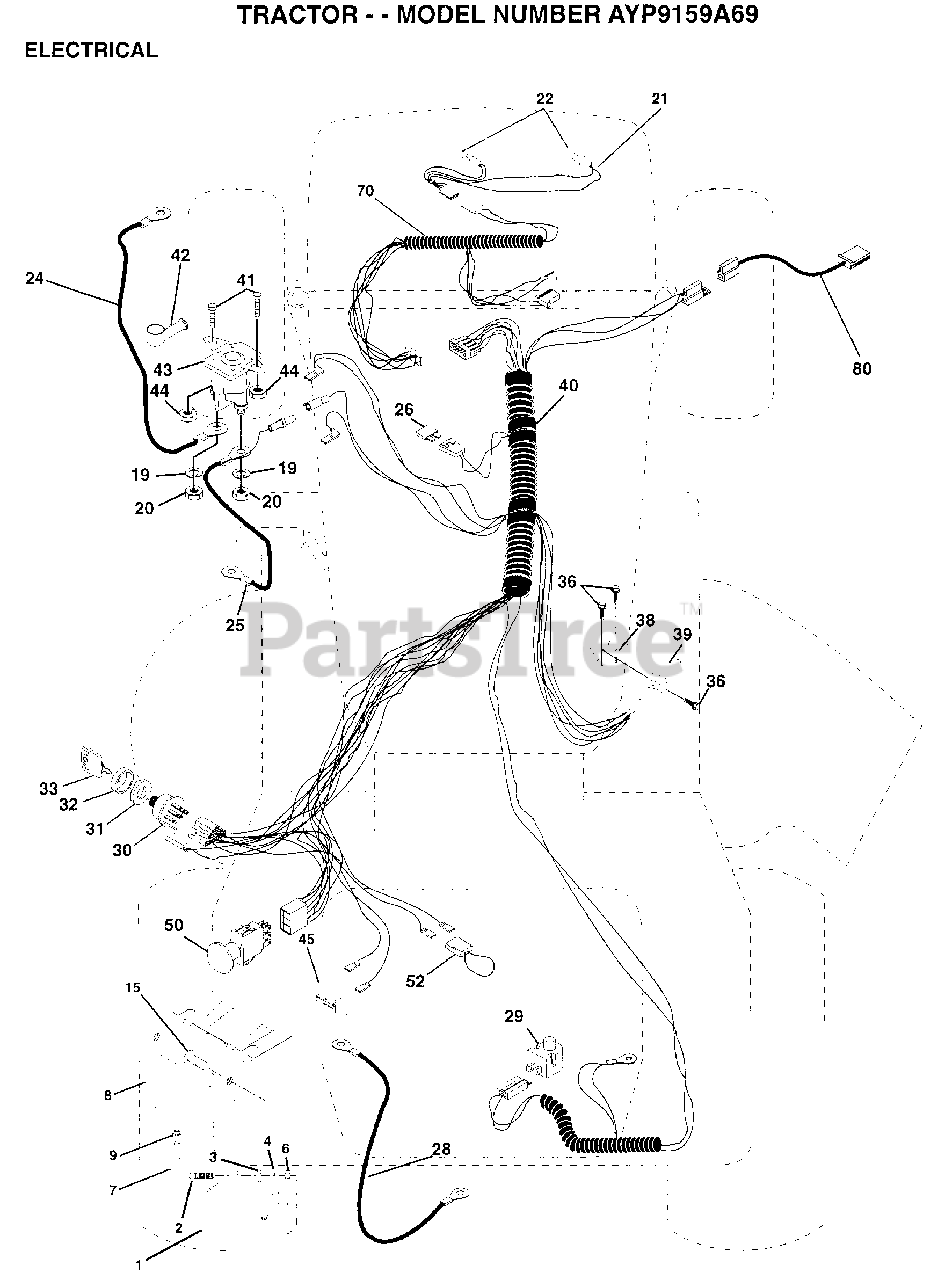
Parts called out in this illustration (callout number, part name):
2	BOLT LT
3	WASHER
4	LOCKWASHER
7	TUBE T
9	HOSE CLAMP T
15	FASTNER.SNAP-IN
20	NUT
21	"HARNESS,LIGHT SOC"
22	HEADLAMP BULB
24	"CABLE T, BATTERY"
25	CABLE.BTRY.6GA.RD
26	FUSE HYT
28	CABLE T
29	SWITCH SEAT
30	SWITCH IGN 4POS
31	NUT IGNITION
32	COVER KEY SWITCH
33	KEY
36	SCREW
38	BRACKET SWITCH IN
39	SWITCH INTERLOCKT
40	IGNITION HARNESS
41	BOLT HXHD FIN
44	NUT HXKEP 1/4X20
46	PROTECTION LOOP
70	HARNESS ENGINE
80	HARNESS.CLUT.EVX.
